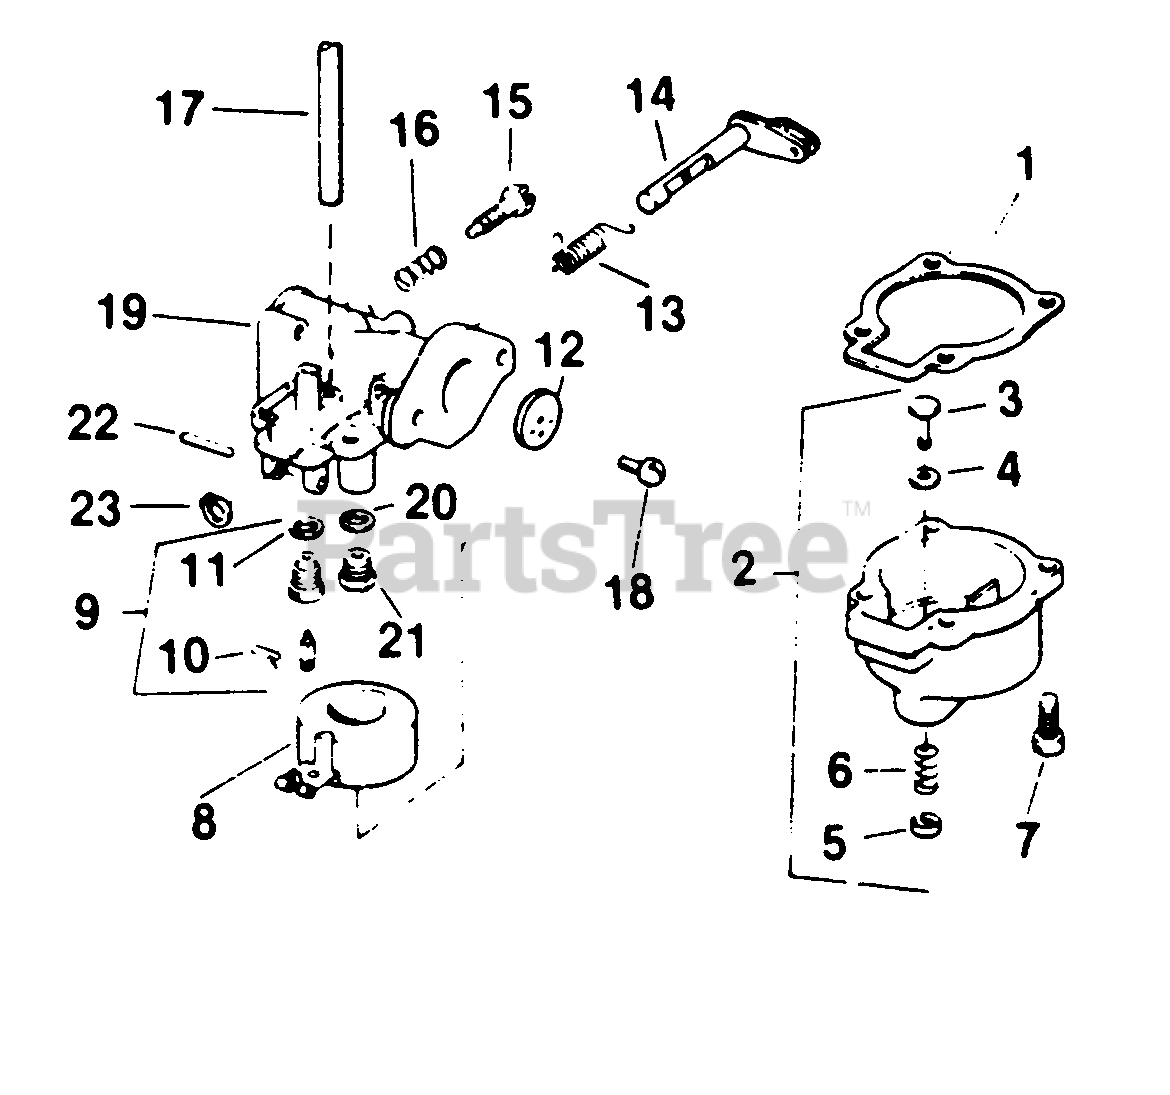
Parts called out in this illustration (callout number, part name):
1	Gasket
2	Float Chamber & Dump Valve Assy.
3	Valve Stem
4	Valve Seat
5	Valve Keeper
6	Valve Spring
7	Screw
8	Float & Arm Assy.
9	Float Valve & Seat Assy.
10	Clip
11	Washer
12	Disc.
13	Spring
14	Shaft
15	Screw
16	Spring
17	Fuel Hose
18	Screw
19	Carburetor Body Assy.
20	Washer
21	Plug
22	Float Pin
23	Grip Ring
